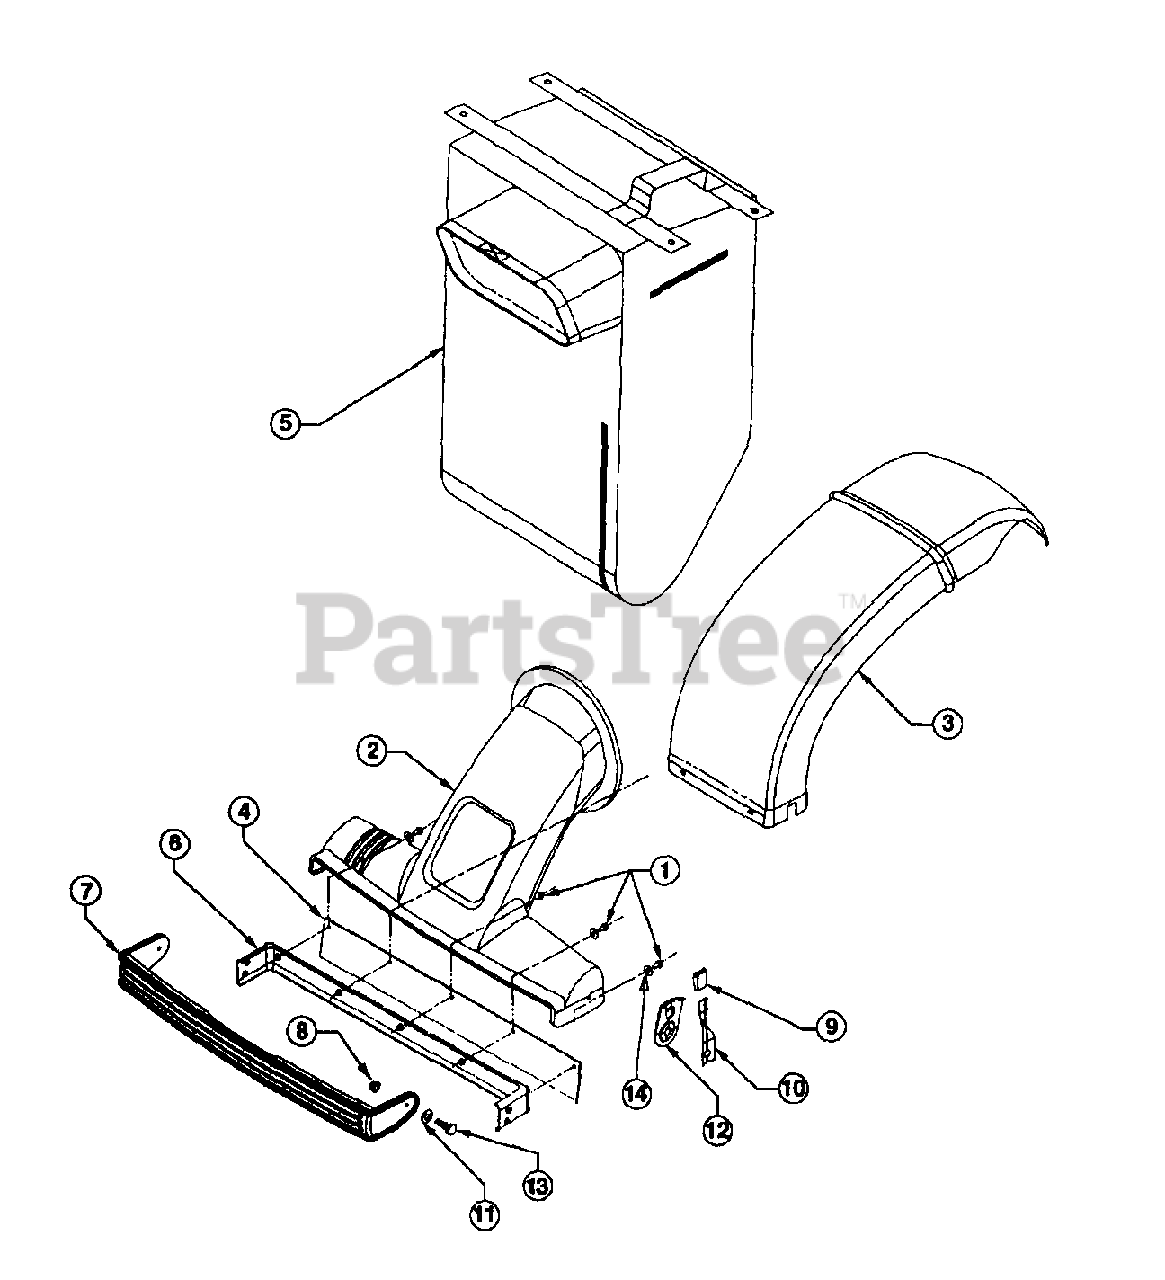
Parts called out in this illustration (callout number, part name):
1	HEX WASHER SCREW
2	NOZZLE ASSEMBLY
3	CHUTE
4	NOZZLE FLAP
5	VACUUM BAG
8	FLANG. LOCK NUT
9	HEIGHT ADJ. KNOB
10	SPRING LEVER
11	FL-WASHER
12	NOZZLE DOOR BRKT.
13	SHOULDER SCREW
14	FLAT WASHER
